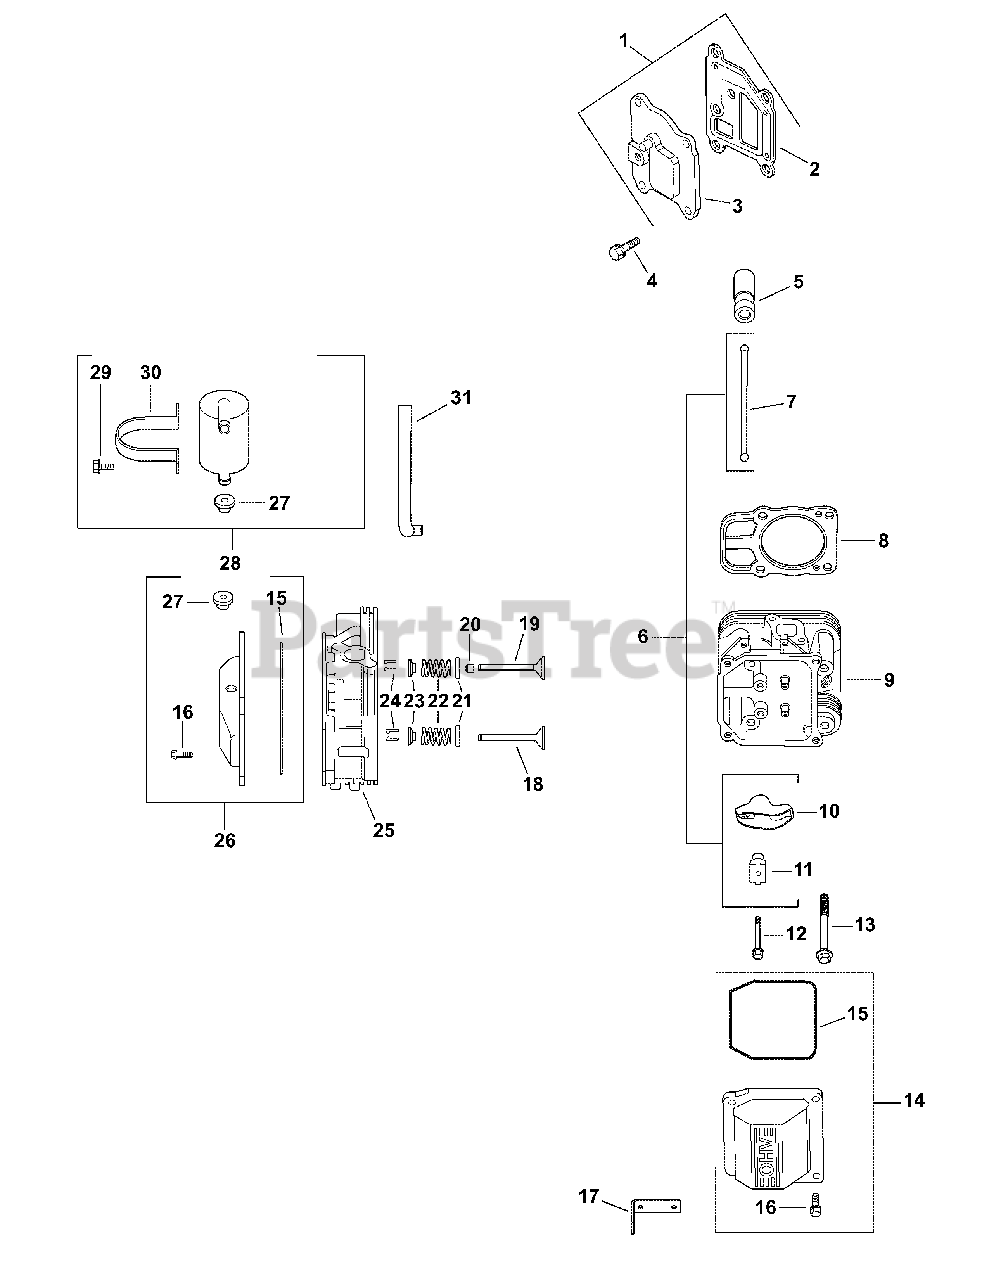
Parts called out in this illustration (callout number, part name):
1	KIT, BREATHER COVER W/GASKET
2	GASKET, BREATHER
3	COVER, BREATHER
4	SCREW, FLG THD FRM M6X1.0X20
5	KIT, HYDRAULIC VALVE LIFTER
6	KIT, VALVE TRAIN
8	KIT, GASKET CYLINDER HEAD
9	KIT, HEAD #2 (Includes KH-25-072-04-S)
11	PIVOT, ROCKER ARM
12	SCREW, FLG M6X1.0X34
13	SCREW, FLG M10X1.5X90
14	KIT, VALVE COVER-PLAIN
15	O-RING, VALVE COVER
16	SCREW, FLG M6X1.0X30
17	STRAP, LIFTING
18	VALVE, EXHAUST (STD)
18	VALVE, EXHAUST (.25)
19	VALVE, INTAKE (STD)
19	VALVE, INTAKE (.25)
20	SEAL, VALVE STEM
21	RETAINER, SPRING
22	SPRING, VALVE
23	CAP, VALVE SPRING
24	KIT, RETAINER
25	KIT, HEAD #1
26	KIT, VALVE COVER BREATHER
27	GROMMET, RUBBER
28	KIT, BREATHER SEPERATOR
29	SCREW, FLG M6X1.0X16
30	STRAP, BREATHER
31	HOSE BREATHER
